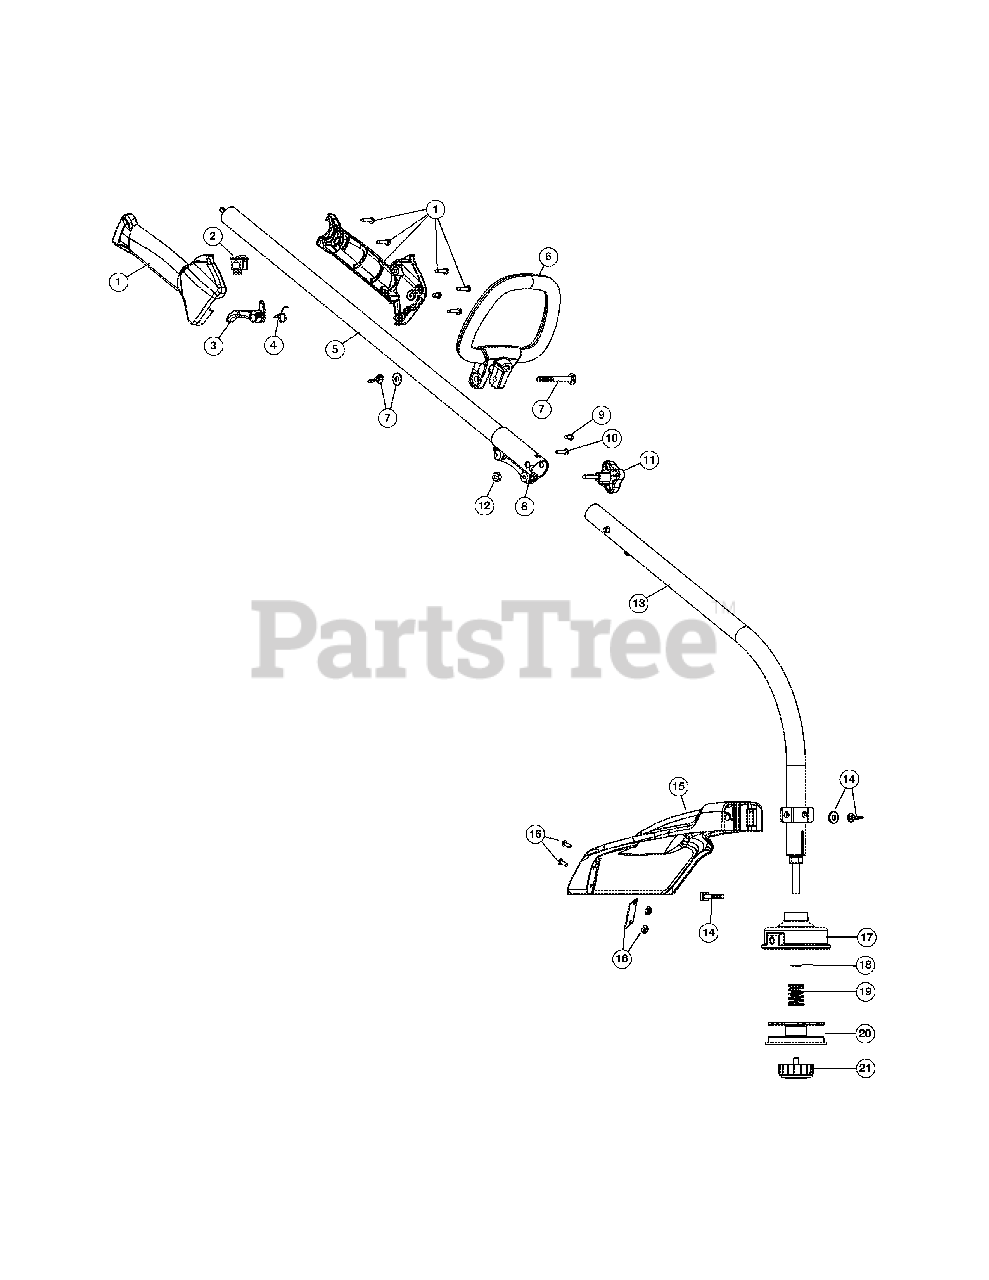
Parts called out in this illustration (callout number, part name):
1	Throttle Housing Assembly (Incl. Ref No. 2-4)
3	Throttle Trigger
4	Throttle Trigger Spring
5	Upper Shaft Housing Assembly
6	D-Handle (Incl. Ref No. 7)
7	D-Handle Hardware Assembly
8	Split Boom Coupler (Incl. Ref No. 9-12)
9	Anti-Rotation Screw
11	Adjustment Knob
12	Knob Retainer Nut
13	Lower Shaft Housing Assembly
14	Shield Mounting Hardware
15	Shield Assembly (Incl. Ref No. 16)
16	Blade Assembly
17	Outer Spool Assembly (Incl. Ref No. 18)
20	Inner Reel
21	Bump Head Knob Assembly
